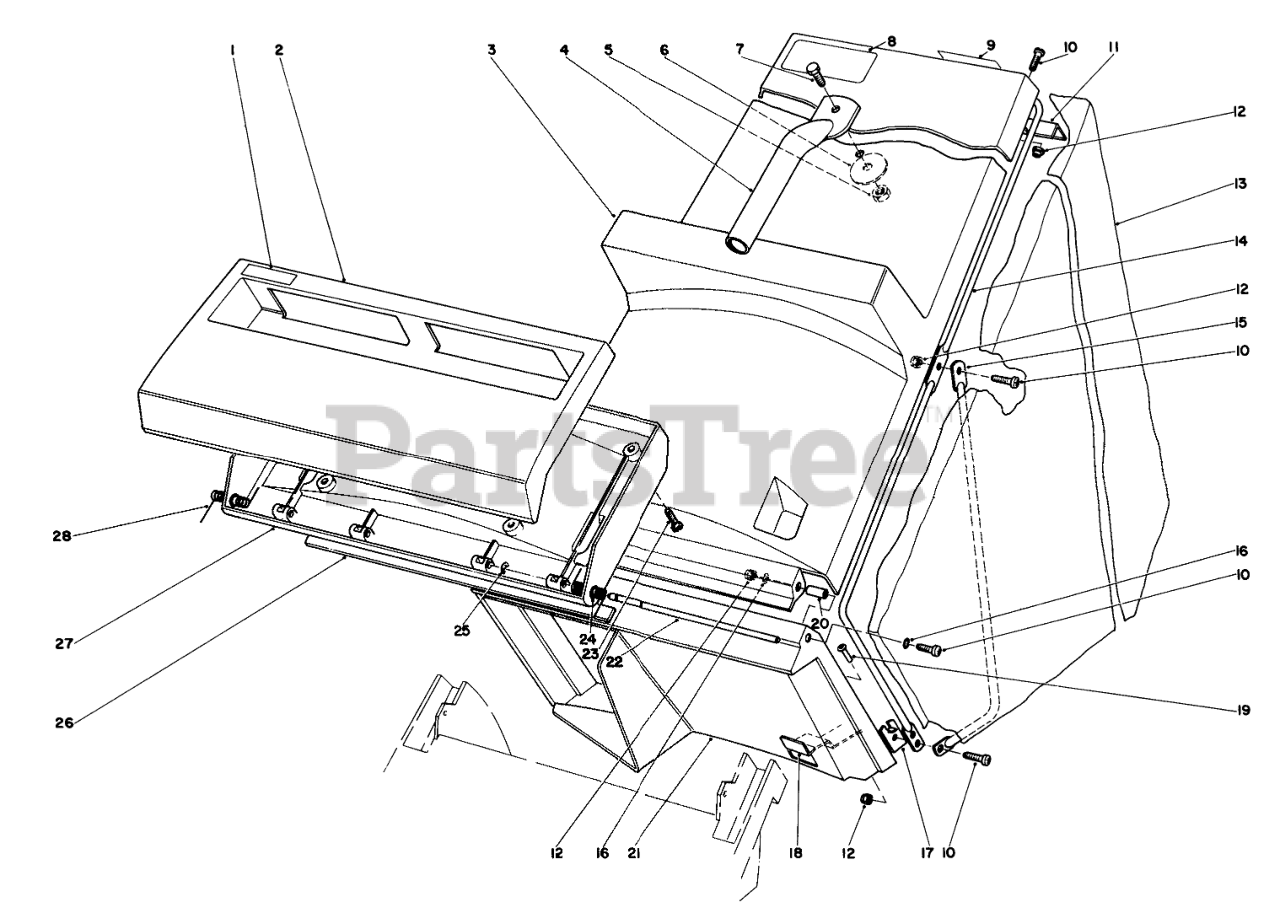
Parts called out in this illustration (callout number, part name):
1	Decal-Danger
2	Door Half-Outside
3	HOUSING-GRASS CATCHER
4	Handle-Grass Catcher
5	M6 X 1 LOCKNUT
6	WASHER-FLAT
7	M6 X 1 HEX HD CAPSCRW
8	Decal-Logo
9	Decal-Waming
10	SCREW-PPH
11	Hinge-Bracket
12	NUT-LOCK
13	BAG ASM
14	Bag Support-Upper
15	Bag Support-Lower
16	WASHER-FLAT
17	Bag Support-Front
18	DOOR LATCH
20	Spacer
21	DOOR GRASS CATCHER
22	Pin-Door Hinge
23	SCREW-PPH
24	LH TORSION SPRING
25	EXT RET E-RING
26	DOOR SEAL
27	DOOR HALF
28	TORSION SPRING RH
